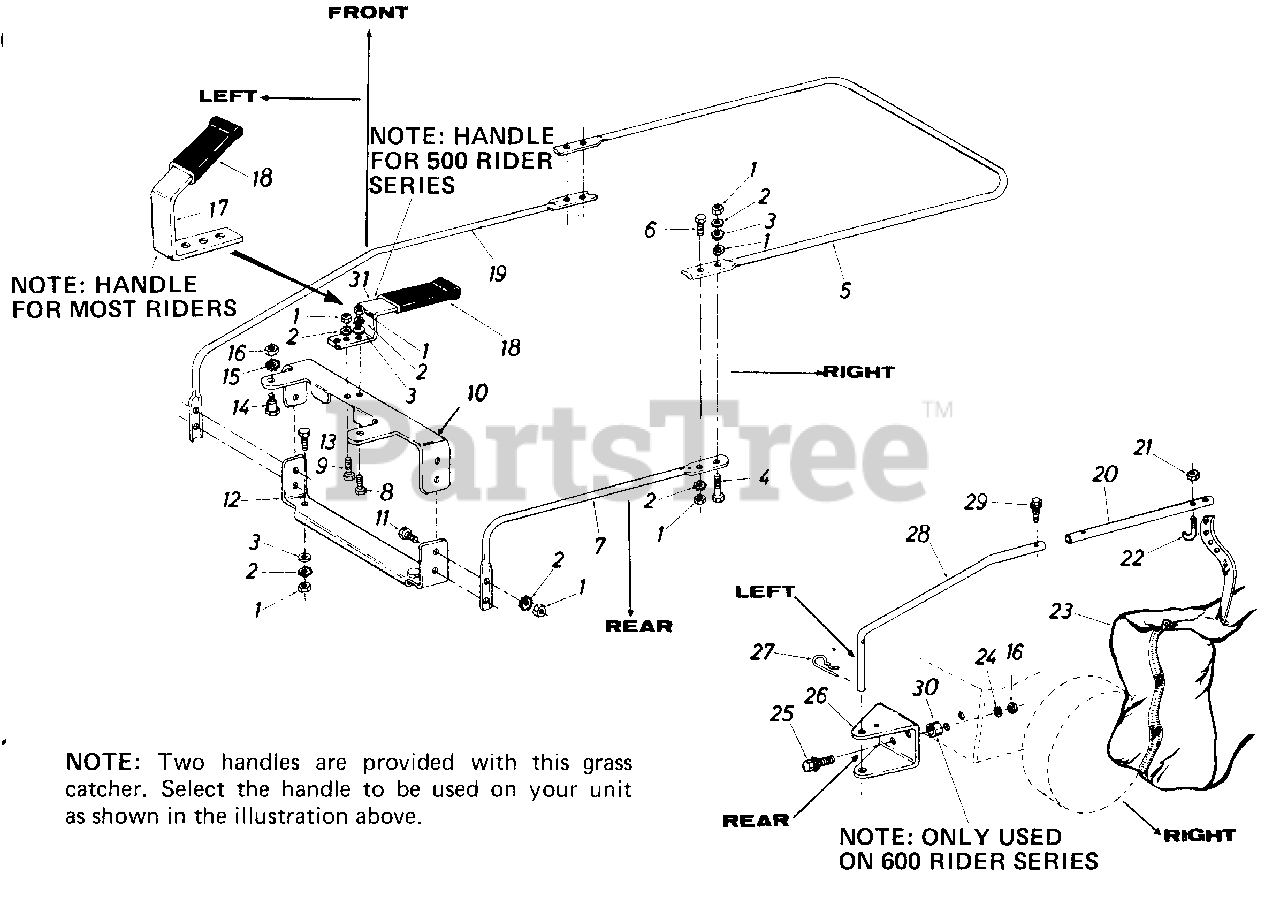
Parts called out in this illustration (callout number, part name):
1	Hex Nut 1/4-20 Thd.
2	Ext. L-Wash. 1/4" Scr.
3	Fl-Wash. .281 I.D. x .50 O.D.
4	Hex Scr. 1/4-20 x 1.50" Lg.
5	Upper Frame Half
6	Hex Scr. 1/4-20 x 1.00" Lg.
7	Lower Frame Tubing
8	Hex Scr. 1/4-20 x .75" Lg.
9	Hex Scr. 1/4-20 x .75" Lg.
10	UpperOpening Support
11	Hex Scr. 1/4-20 x 1.0" Lg.
12	Lower Opening Support
13	Hex Scr. 1/4-20 x .50" Lg.
14	Shld. Scr. .437 Dia. x .350
15	Ext. L-Wash. 5/16" Scr.
16	Hex Nut 5/16-18 Thd.
19	Lower Frame Arm
23	Grass CatcherBag
24	L-Wash. 5/16" I.D.
25	Hex Sems S.cr. 5/16-18 x .75" Lg.
26	Hitch Bracket
27	Internal Cotter Pin 5/8" Dia.
28	Lower Holding Arm
29	Hex Wash. Hd. Self-Tap .50" Lg.
30	Spacer
31	Handle
